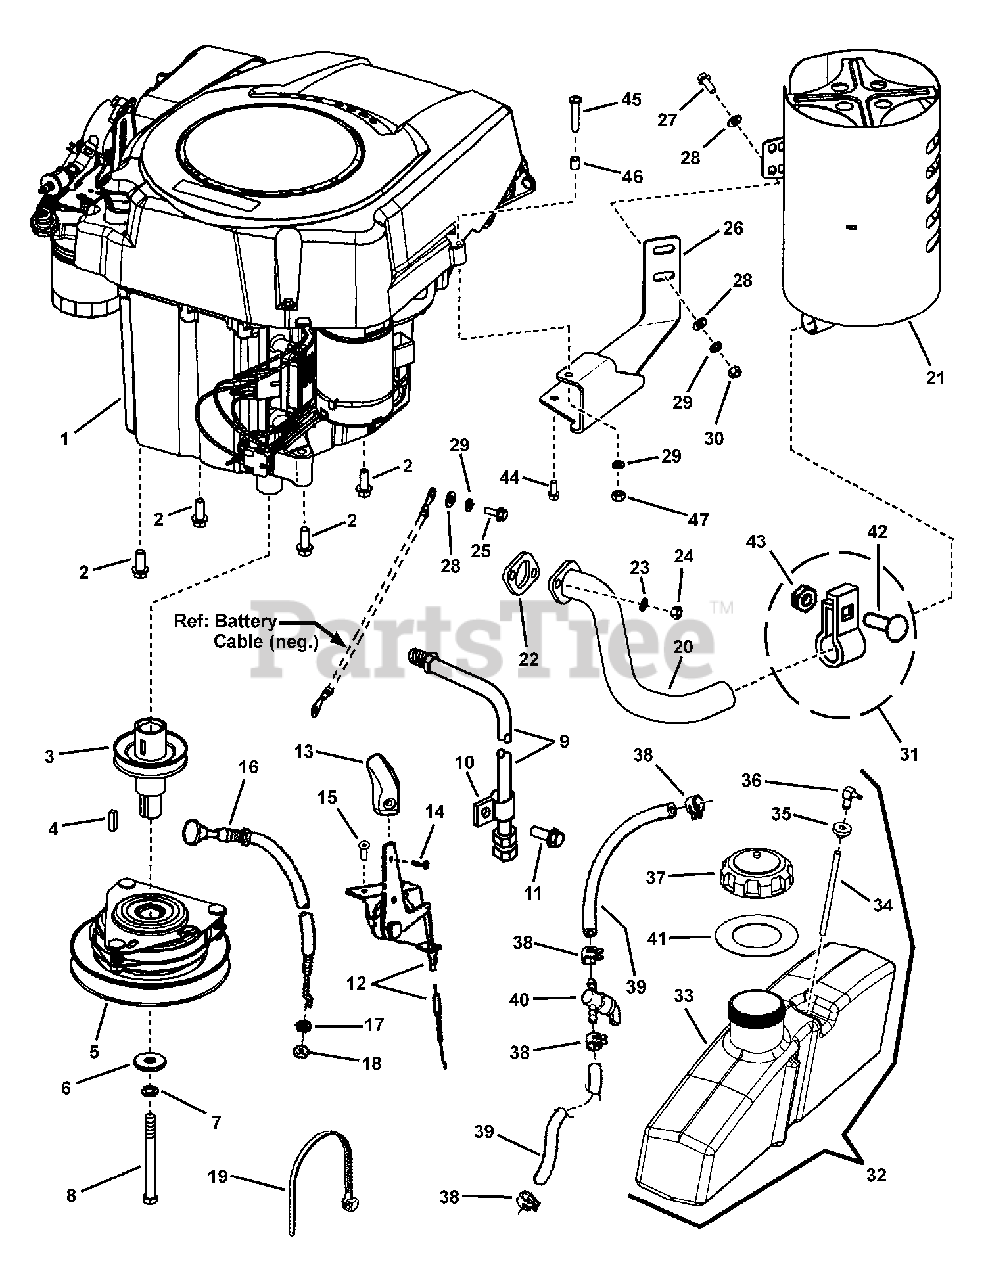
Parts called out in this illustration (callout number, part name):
2	CAPSCREW, Hex Head Flange Taptite, 3/8C X1 BZ
3	PULLEY, Engine
4	KEY, Square, 1/4X1
5	CLUTCH, # 504586, Electric, Ogura JD-11
6	WASHER, .468X1.50X.19 YZ
7	WASHER, Lock, .445X.776X.1 YZ
8	CAPSCREW, Hex Head, 7/16F X4-1/2, GR5 YZ
9	HOSE, Oil Drain .375ID 16.5L
10	CLIP, Harness, 5/8
11	BOLT, 5/16-18 x 5/8" Hex Flange Lock, GR 5
12	THROTTLE CONTROL, 26.25
13	KNOB, Throttle, Red, RZT
14	CAPSCREW, Pan Head Self-Tapping, Combo, #10-16 X3/4 BZ
15	CAPSCREW, Pan Head Self-Tapping, TORX, 1/4C X5/8 BP
16	CONTROL, Choke, 30
17	WASHER, Lock, Internal Tooth, 3/8 BZ
18	NUT, Hex, 3/8F GR.B BZ
19	CABLE TIE, 7.0
20	MANIFOLD, 20 HP Kohler
21	MUFFLER, LC YZ
22	GASKET, Exhaust
23	WASHER, Lock, .32X.58X.08 YZ
24	NUT, Hex, 5/16C GR5 YZ
25	SCREW, Self Tap, M6 X 1.0 X 15MM LG
26	BRACKET, Muffler, Kohler 20 HP
27	CAPSCREW, Hex Head 1/4-20 x 1"
28	WASHER, .28X.63X.065 YZ
29	WASHER, Lock, .256X.487X.062 ZP
30	NUT, Hex, 1/4C GR5 YZ
31	CLAMP ASSEMBLY, B&S# 223434,93877,93203
32	FUEL TANK ASSEMBLY, RZT
33	FUEL TANK
36	ELBOW, 90 Degree
37	CAP, Fuel, 3-1/2"
38	CLAMP, Fuel Hose
39	HOSE, Fuel 5
40	VALVE, Fuel
42	CARRIAGE BOLT, 5/16C X1-1/4 GR5 YZ
43	NUT, Hex Flange Lock, 5/16C GR5 YZ
44	SCREW, 1/4-20 x 1/2" Hex Flange Lock, GR 5
45	SCREW, Machine, M6-1.0 X 35 MM BZ
46	SPACER, .344 OD X .250 ID X .410
